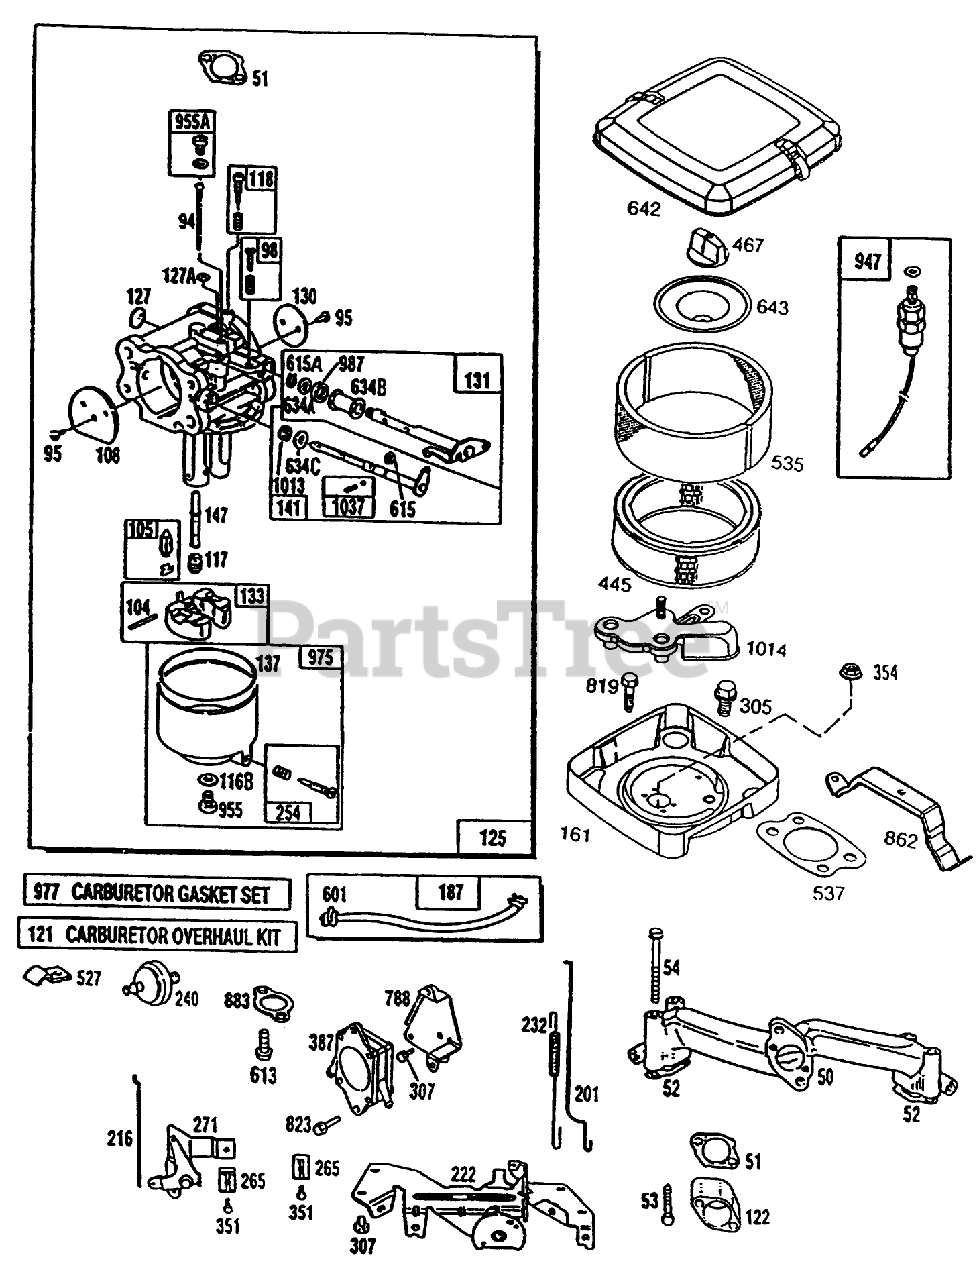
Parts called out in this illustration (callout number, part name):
50	BRIGGS-805409
51	BRIGGS-805149
52	BRIGGS 805023
53	BRIGGS-805360
87	BRIGGS-805054
95	BRIGGS-805561
98	BRIGGS 807705
104	BRIGGS 805586
105	BRIGGS 807706
118	BRIGGS-807707
121	BRIGGS-807962
122	BRIGGS-805329
125	BRIGGS-808255
127	BRIGGS 805570
127A	BRIGGS 805571
131	BRIGGS-807709
133	BRIGGS-807710
137	Gasket-Float Bowl
141	BRIGGS-807711
147	NOZZLE
161	Base-Air Cleaner
201	BRIGGS 805480
216	BRIGGS-805439
222	BRIGGS-807610
254	BRIGGS-807713
305	BRIGGS 805406
307	BRIGGS-78-4310
351	BRIGGS 805169
445	CARTRIDGE-CLEANER, AIR
467	BRIGGS-491875
535	ELEMENT-FILTER
537	BRIGGS 805655
601	BRIGGS-93053
615	BRIGGS 805578
615A	BRIGGS 805577
634A	BRIGGS 805576
634B	BRIGGS-805574
634C	BRIGGS 805580
643	BRIGGS 805631
819	BRIGGS 805057
823	BRIGGS 805317
955	BRIGGS 805592
955A	BRIGGS-807714
975	BRIGGS-807715
977	BRIGGS 807716
987	BRIGGS 805575
1013	BRIGGS 805581
1037	BRIGGS 807717
